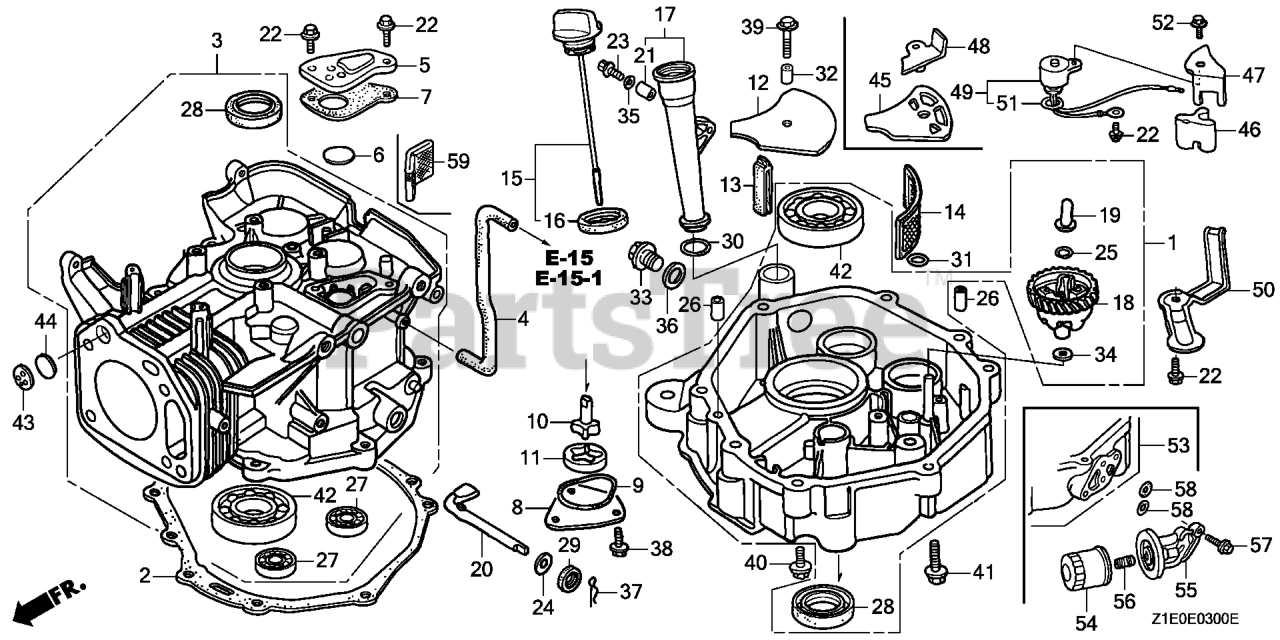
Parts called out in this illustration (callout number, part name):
2	GASKET, OIL PAN
3	CYLINDER ASSY.
4	TUBE, BREATHER
5	CAP, BREATHER CHAMBER
6	VALVE, BREATHER
7	GASKET, BREATHER CAP
8	COVER, OIL PUMP
9	O-RING, PUMP COVER
10	ROTOR (INNER)
11	ROTOR, OIL PUMP (OUTER)
13	RUBBER, OIL RETURN
14	SCREEN, OIL FILTER
15	CAP ASSY., OIL FILLER
16	GASKET, OIL FILLER CAP
17	EXTENSION, OIL FILLER
18	GOVERNOR ASSY.
19	SLIDER, GOVERNOR
20	SHAFT, GOVERNOR ARM
21	COLLAR, EXTENSION Use up to Engine SN 1257294.
22	BOLT, FLANGE (6X12) (CT200)
23	BOLT, FLANGE (6X35)
24	WASHER, THRUST (8.1MM)
25	CLIP, GOVERNOR HOLDER
26	PIN, DOWEL (8X12)
27	BEARING, RADIAL BALL (6202)
28	OIL SEAL (35X52X8) (NOK)
29	OIL SEAL (8X14X5)
30	O-RING (22.5X2.2) Use from Engine SN 1257295.
31	O-RING (11.8X2.4)
33	BOLT, DRAIN PLUG (20MM)
34	WASHER, PLAIN (6MM)
35	WASHER, PLAIN (6MM)
36	WASHER, DRAIN PLUG (20MM)
37	PIN, LOCK (10MM)
38	BOLT, FLANGE (6X12) Use up to Engine SN 1543277.
39	BOLT, FLANGE (6X25)
40	BOLT, FLANGE (8X40)
41	BOLT, FLANGE (8X60)
42	BEARING, RADIAL BALL (6207)
43	PLATE, ONE-WAY VALVE
44	VALVE, ONE-WAY
45	PLATE, OIL FILTER
46	STOPPER, OIL
47	PLATE, OIL STOPPER
48	PLATE, SUCTION
49	SWITCH, OIL LEVEL
50	PROTECTOR, SWITCH
51	O-RING (11.8X2.4)
52	BOLT, FLANGE (6X16) Use from Engine SN 2056820.
53	PAN ASSY., OIL
54	FILTER, OIL
55	BASE, OIL FILTER
56	HOLDER, OIL FILTER
57	BOLT, FLANGE (6X25) Use up to Engine SN 2056819.
58	O-RING (1.9X11)
58	O-RING (11X1.9) (NOK)
